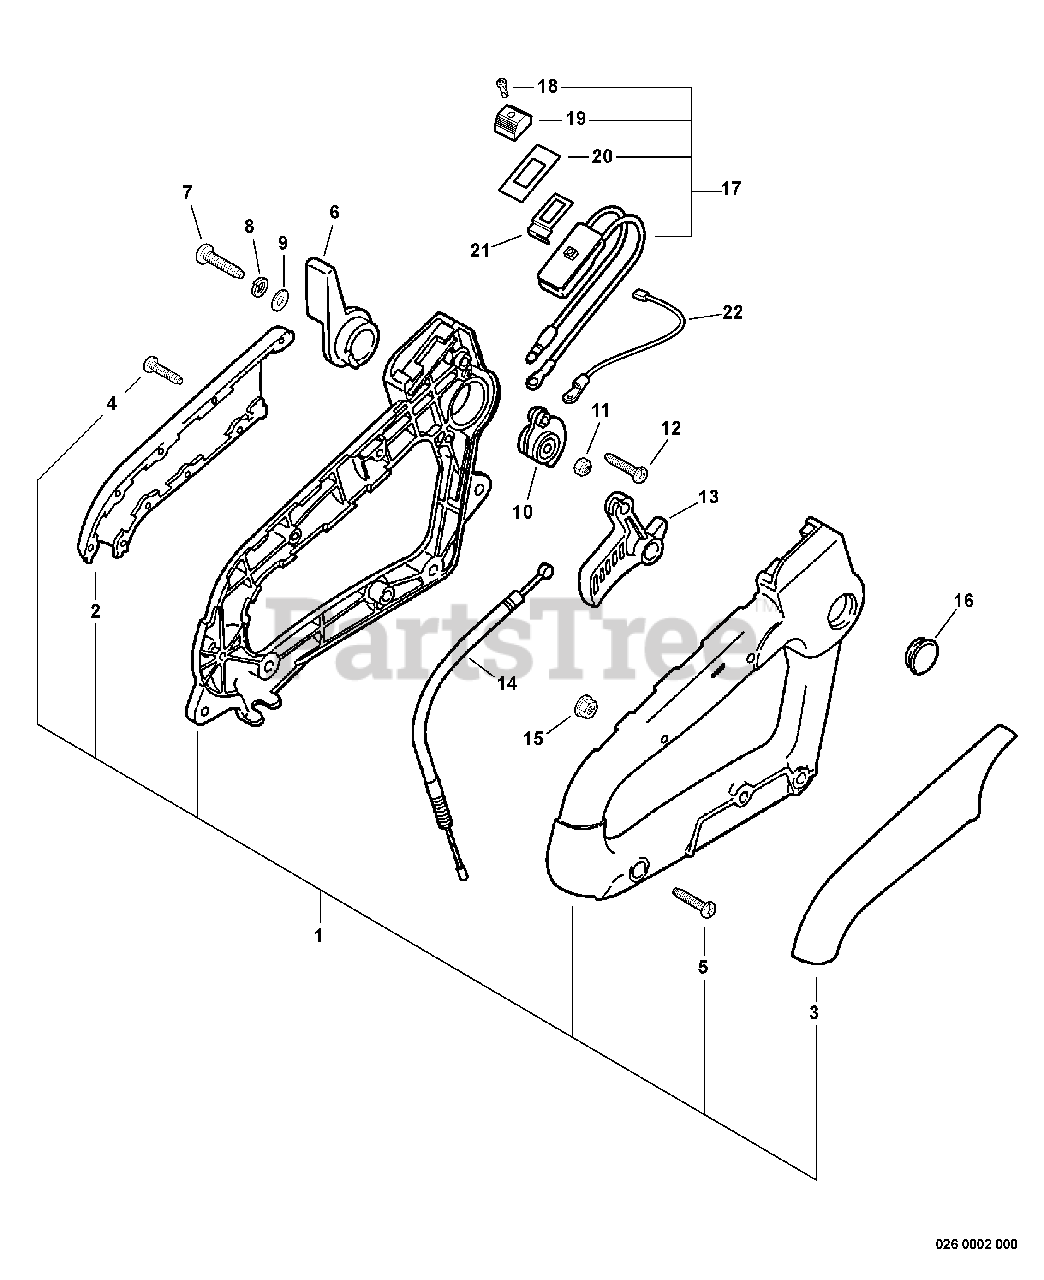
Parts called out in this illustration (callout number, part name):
1	HANDLE SET - REAR
2	GRIP, HANDLE - LEFT
3	GRIP, HANDLE - RIGHT
4	SCREW - 4X22
5	SCREW - 5X30
6	CONTROL, THROTTLE
7	SCREW - 6X20
8	LOCKWASHER - 6
9	WASHER - 6
10	BRACKET, THROTTLE
11	NUT - 6
12	SCREW - 4X10
13	TRIGGER, THROTTLE
14	CABLE, THROTTLE
15	NUT - 5 -- FLANGE
17	IGNITION SWITCH ASSY
18	SCREW - 3X10
19	KNOB, SWITCH - ORANGE
20	COVER, SWITCH - STOP
21	TERMINAL - GROUND
22	LEAD - ANTI-STATIC
